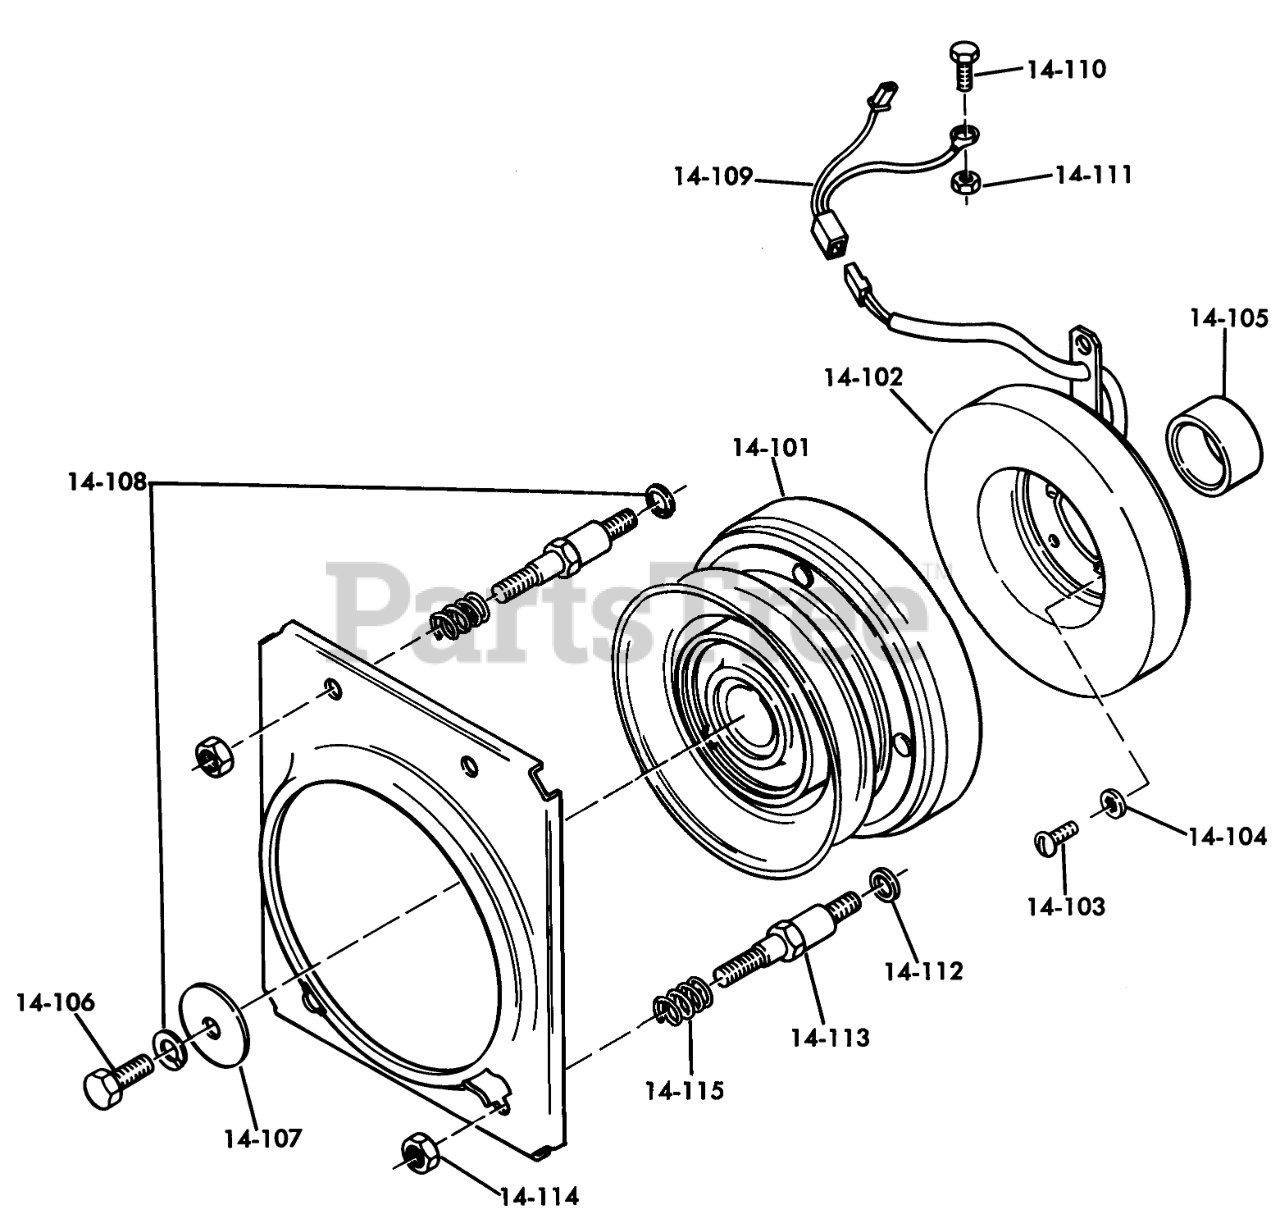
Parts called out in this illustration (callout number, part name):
14-101	Rotor Assembly
14-102	Field Assembly
14-103	Screw
14-104	Lockwasher Internal
14-105	Sleeve
14-106	BOLT
14-107	Washer .406 x 1.75 x .187
14-108	LOCKWASHER
14-109	Assy-Wire and Plug
14-110	Bolt
14-111	Nut
14-112	Washer-Copper
14-114	NUT
14-115	Spring
